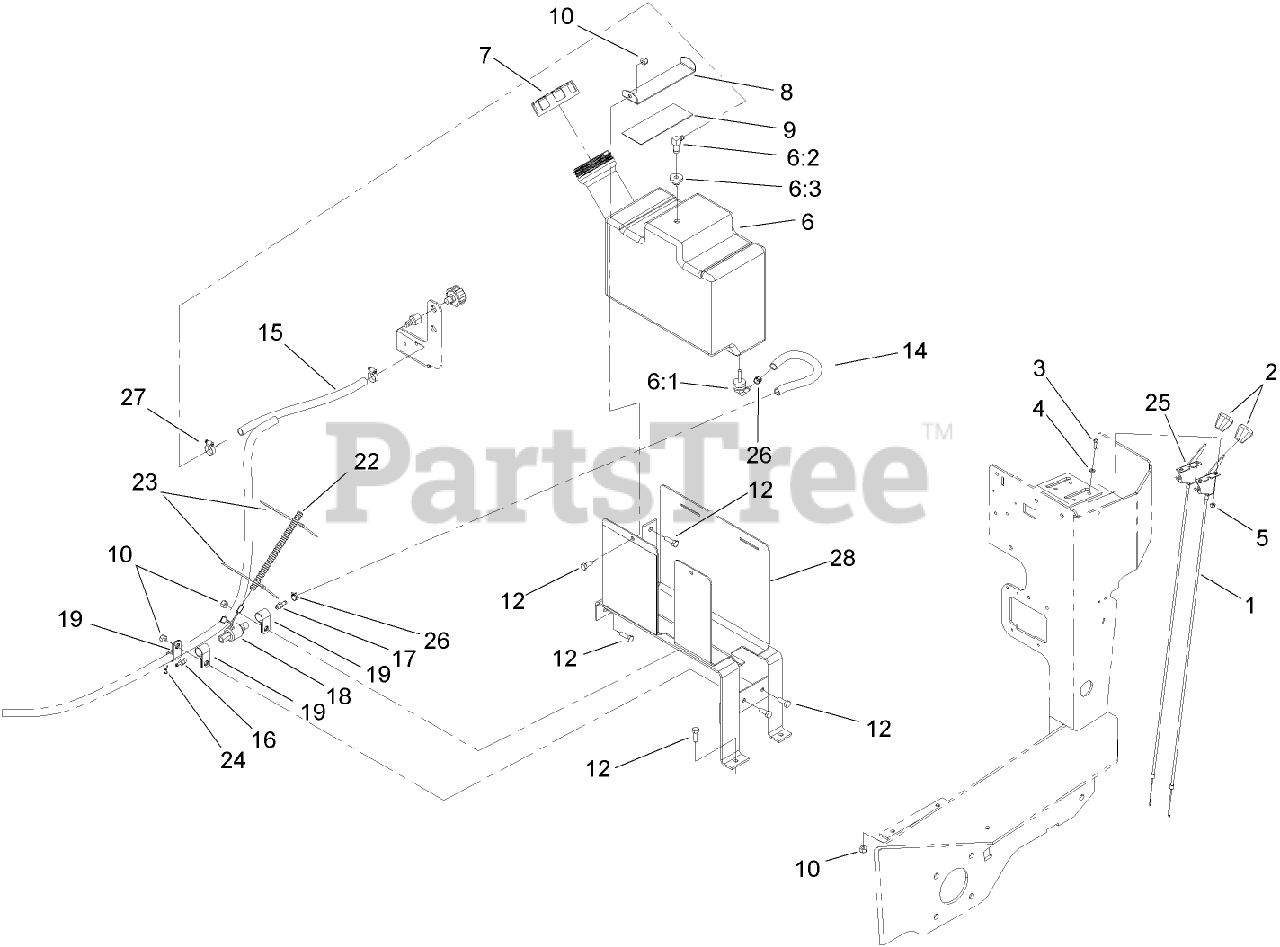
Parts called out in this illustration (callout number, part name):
1	CABLE-CHOKE
4	WASHER-FLAT
5	NUT-LOCK, NI
6	FUEL TANK ASM
6:1	FITTING-FUEL, BULKHEAD
6:2	FITTING-90 DEGREE
6:3	BUSHING
7	UNLEADED GAS CAP ASM
8	STRAP-TANK
9	FELT-STRAP
10	NUT-LOCK, NI
12	SCREW-HH
14	HOSE - GAS
15	HOSE-FUEL
16	FITTING-BARBED
17	FITTING-STRAIGHT
18	VALVE-SHUTOFF, FUEL
19	CLAMP-R
22	COVER-BRACE
23	TIE-CABLE
24	CLAMP-HOSE
25	CABLE-THROTTLE
26	CLAMP-HOSE
27	CLAMP-HOSE
28	TANK BRACKET ASM
